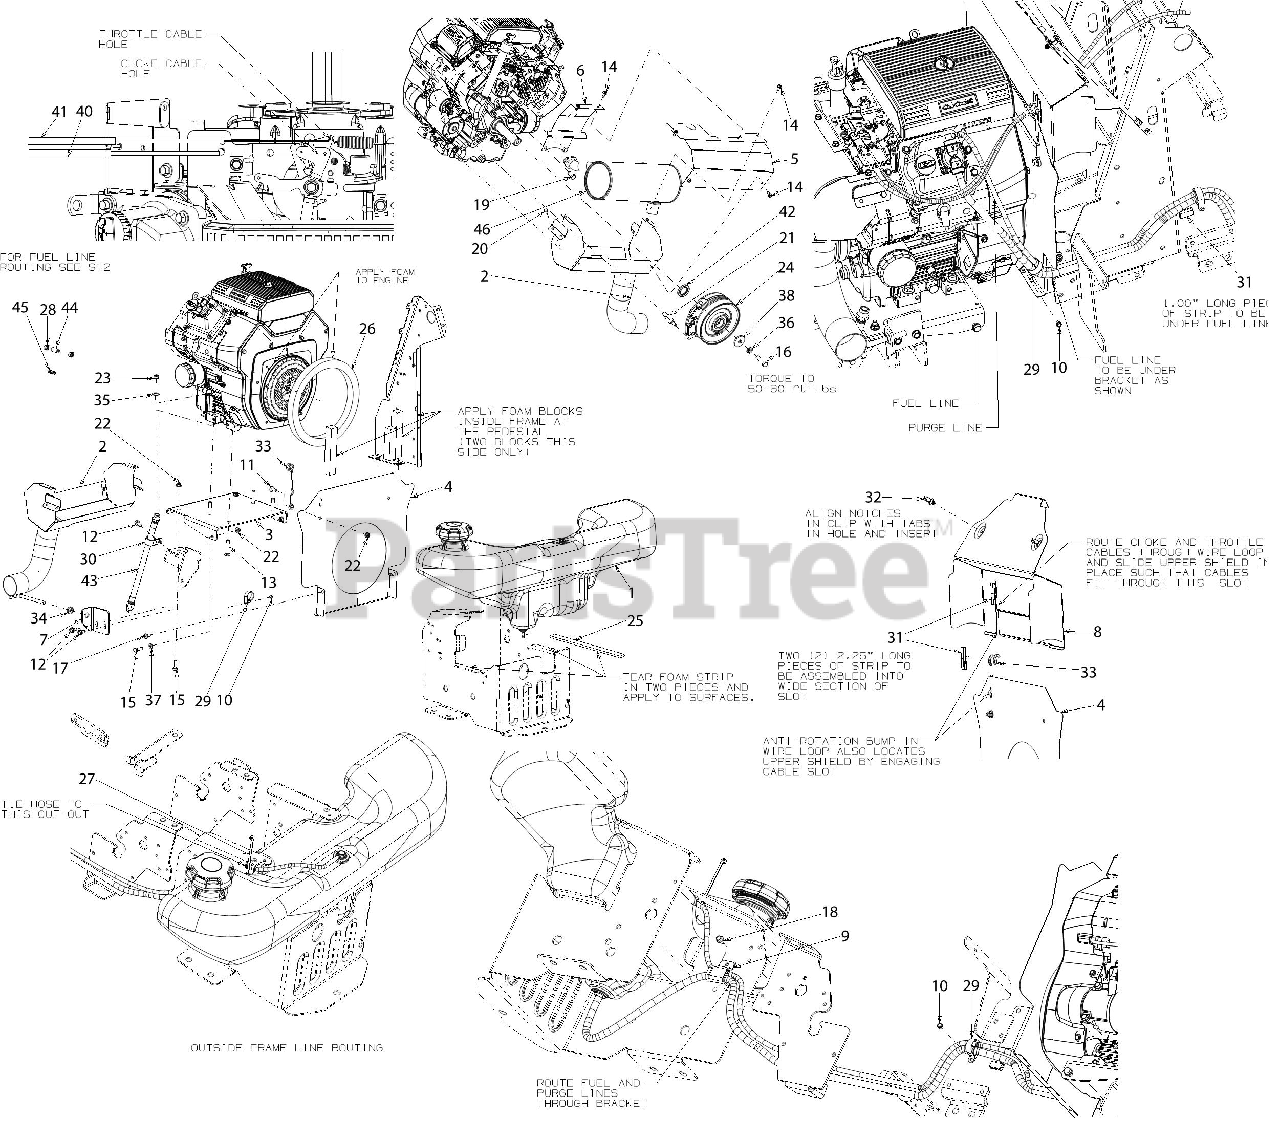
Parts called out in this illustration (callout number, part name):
1	FUEL TANK ASSEMBLY
2	EXHAUST PIPE ASSEMBLY
3	ENGINE MOUNTING PLATE
5	UPPER HEAT SHIELD
6	HEAT SHIELD BRACKET
7	EXHAUST PIPE BRACKET
10	HEX SCREW AB-TAP #10-16 x 0.500
11	SCREW 5/16-18
12	SCREW 5/16-18 x .750
13	SCREW 3/8-24 x 1.75 GR5
14	SCREW 1/4-20 X.500
15	SCREW 5/16-18 x 1.00 GR5
16	SCREW 7/16-20 x 1.50 GR5
17	SCREW 5/16-18 x .750
18	SCREW 1/4-20X.625
19	SCREW 3/8-16 x .75 GR 5
20	SCREW M6-1.0X10MM GR8.8
21	CLUTCH STOP STUD
22	FLANGE LOCK NUT 5/16-18
23	HEX LOCK NUT 3/8-2
24	ELECTRIC PTO CLUTCH
25	FOAM TAPE .75" WIDE x .25" THICK
26	FOAM GASKET
27	7" CABLE TIE
28	HOSE CLAMP 1/20
29	DRAIN HOSE CLAMP
30	HOSE CLAMP 1.0"
33	FIXED CABLE GUDIE
35	BELL WASHER .400 ID x .88 x .060
36	LOCK WASHER 7/16
37	FLAT WASHER
38	FLAT WASHER .45 x 1.5 x .172 HT
40	CHOKE CABLE (RED STAMP)
41	THROTTLE CABLE (WHITE STAMP)
42	PTO SPACER
43	OIL DRAIN HOSE
44	FUEL HOSE LOW PERMEATION
45	VENT HOSE 3/16 ID
46	EXHAUST MUFFLER
